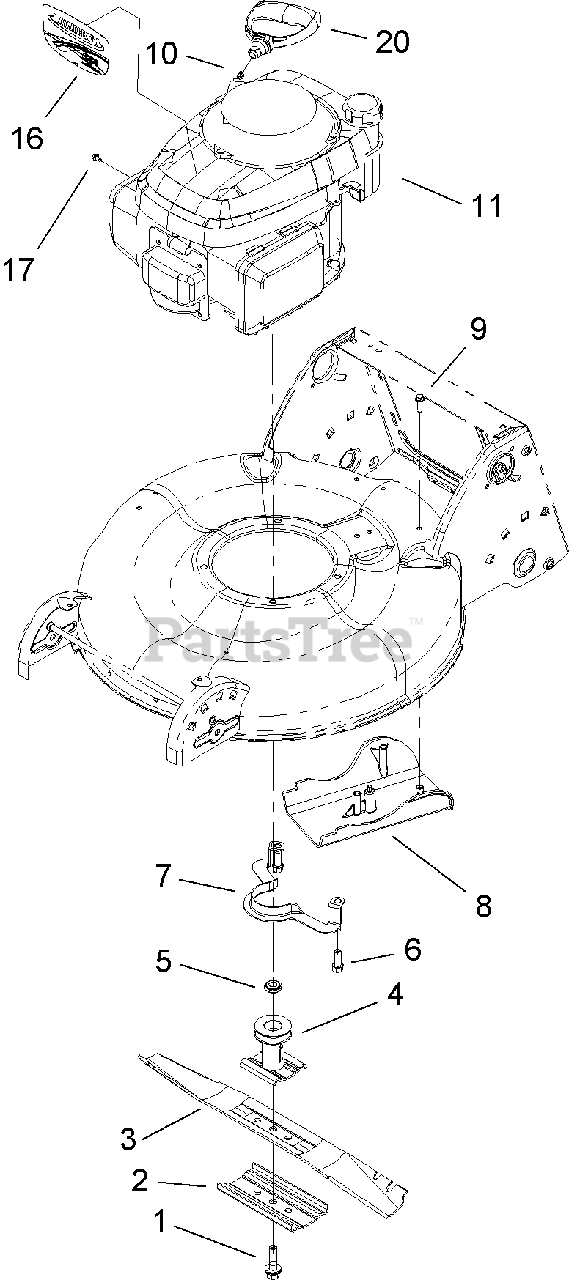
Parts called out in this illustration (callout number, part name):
1	BOLT-BLADE
2	SUPPORT-BLADE
3	BLADE-21 INCH
4	BLADE DRIVER ASM
5	Spacer-Driver
6	SCREW
8	COVER-BELT
9	SCREW-HWH
10	STOP-ROPE
17	SCREW-HWH
20	HANDLE-RECOIL
